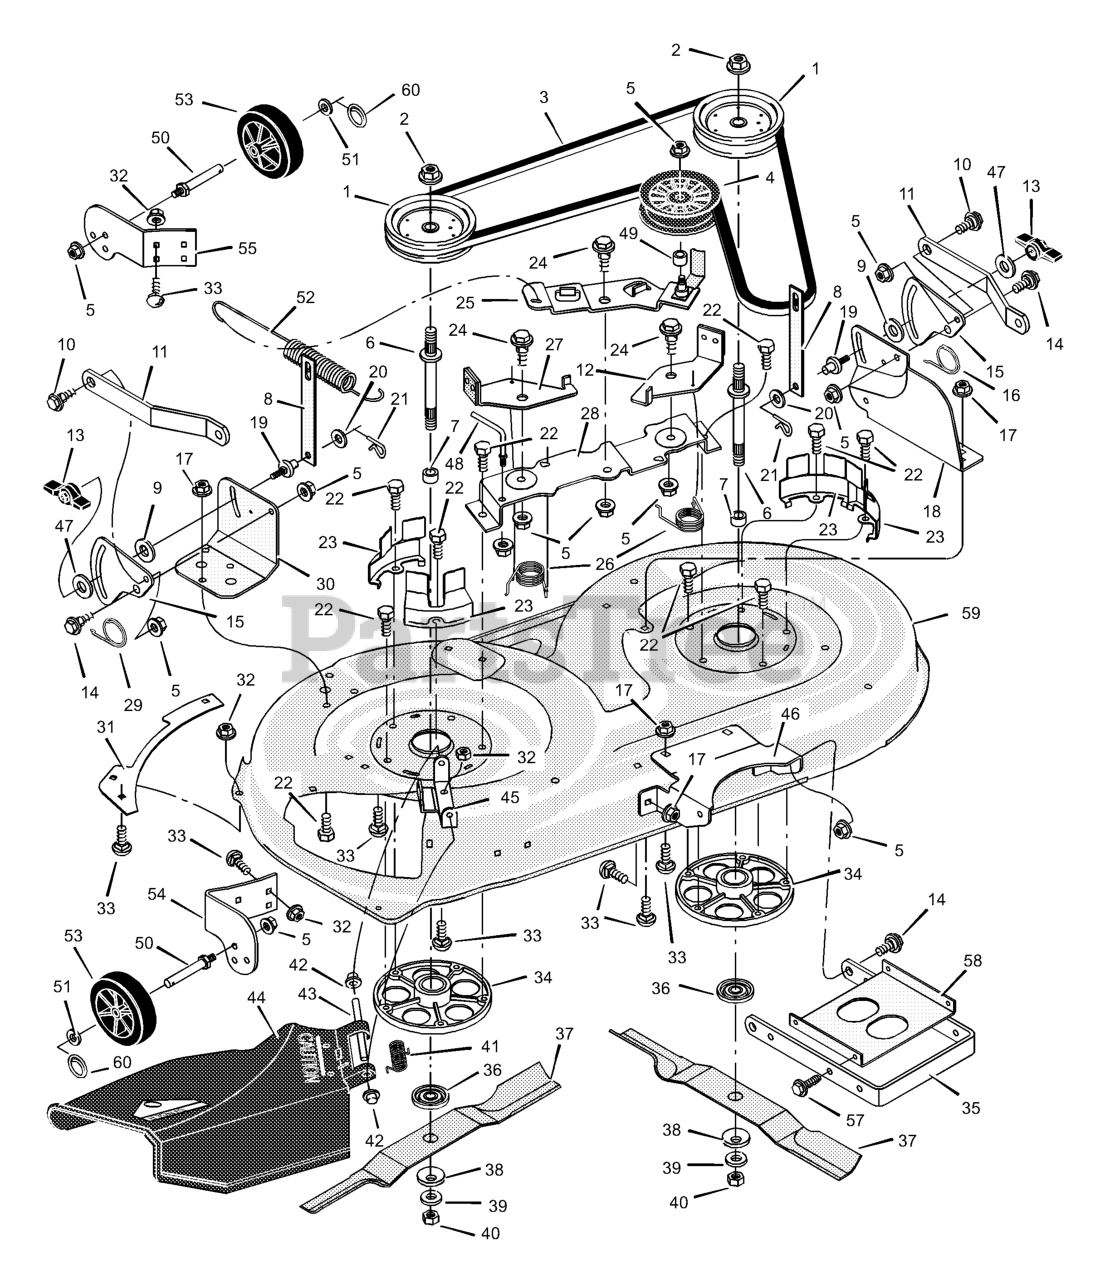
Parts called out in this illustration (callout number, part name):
1	Pulley, Jackshaft
2	NUT, 9/16- 18 UNF- 2B
3	BELT, V Mower Drive, 42" (HA Sect.; 89.19 E.L.)
4	PULLEY, Idler, 4 in
5	NUT, Hex Flange, Center Lock, 3/8-16
6	JACKSHAFT 7.12LG
7	SPACER,.625 X .875 X 1.858
8	Link, Lift
9	FRICTION PAD
10	BOLT, Shoulder, 3/8-16 x 1
11	Bracket, Rear Suspension
12	Pad Assembly, Left Brake
13	KNOB (5/16-18 nut enclosed)
14	BOLT, Shoulder, 3/8-16
15	Plate, Suspension
16	SPRING, Left Torsion
17	NUT, Hex Flange, 5/16-18
18	Bracket, Suspension -LH
19	Pin, Hanger
20	WASHER, Flat, 1/2
21	PIN, Hair
22	SCREW, Self Tap, 3/8-16 x 1-1/4
23	SEGMENT - BELT GUIDE
24	BOLT, Shoulder, 3/8-16 x 1/2
25	Arm, Idler
26	SPRING, Torsion, Brake
27	Pad Assembly, Right Brake
28	BRACKET - BRAKE MTG 42"
29	SPRING, Right Torsion
30	Bracket, Suspension -RH
31	PLATE, Rear
32	NUT, Hex Flange, Center Lock, 5/16-18
33	BOLT, Carriage, 5/16-18 x 5/8
34	Housing, Jackshaft
35	PLATE, Rear
36	Bracket, Suspension
37	BLADE, 42 (3N1)
38	WASHER, Belleville
39	WASHER, Hardened
40	NUT, Blade, 9/16-18
41	SPRING, Torsion
42	CAP, Push On
43	ROD, Deflector
44	DEFLECTOR & SUPPORT ASSEMBLY, Chute
45	BRACKET, Hinge
46	Bracket, Front Hanger
47	WASHER, Flat, 1
48	BELT GUIDE (5/16-18)
49	SPACER, 1/2 in To 17 mm
50	BOLT, Gauge Wheel
51	WASHER, Flat, .81 x .550 x 16GA
52	SPRING EXTENSION, 9.43L X 0.62D
53	WHEEL, Gauge
54	BRKT RH GAGE WHEEL 42"
55	Bracket, Left Wheel
57	CAPSCREW, Hex Head, 5/16-18 x 3/4
58	Brace, Hanger
59	Housing, Blade, Complete (NO LONGER AVAILABLE)
59	Housing, Blade (Housing Only)
60	HAIR PIN
